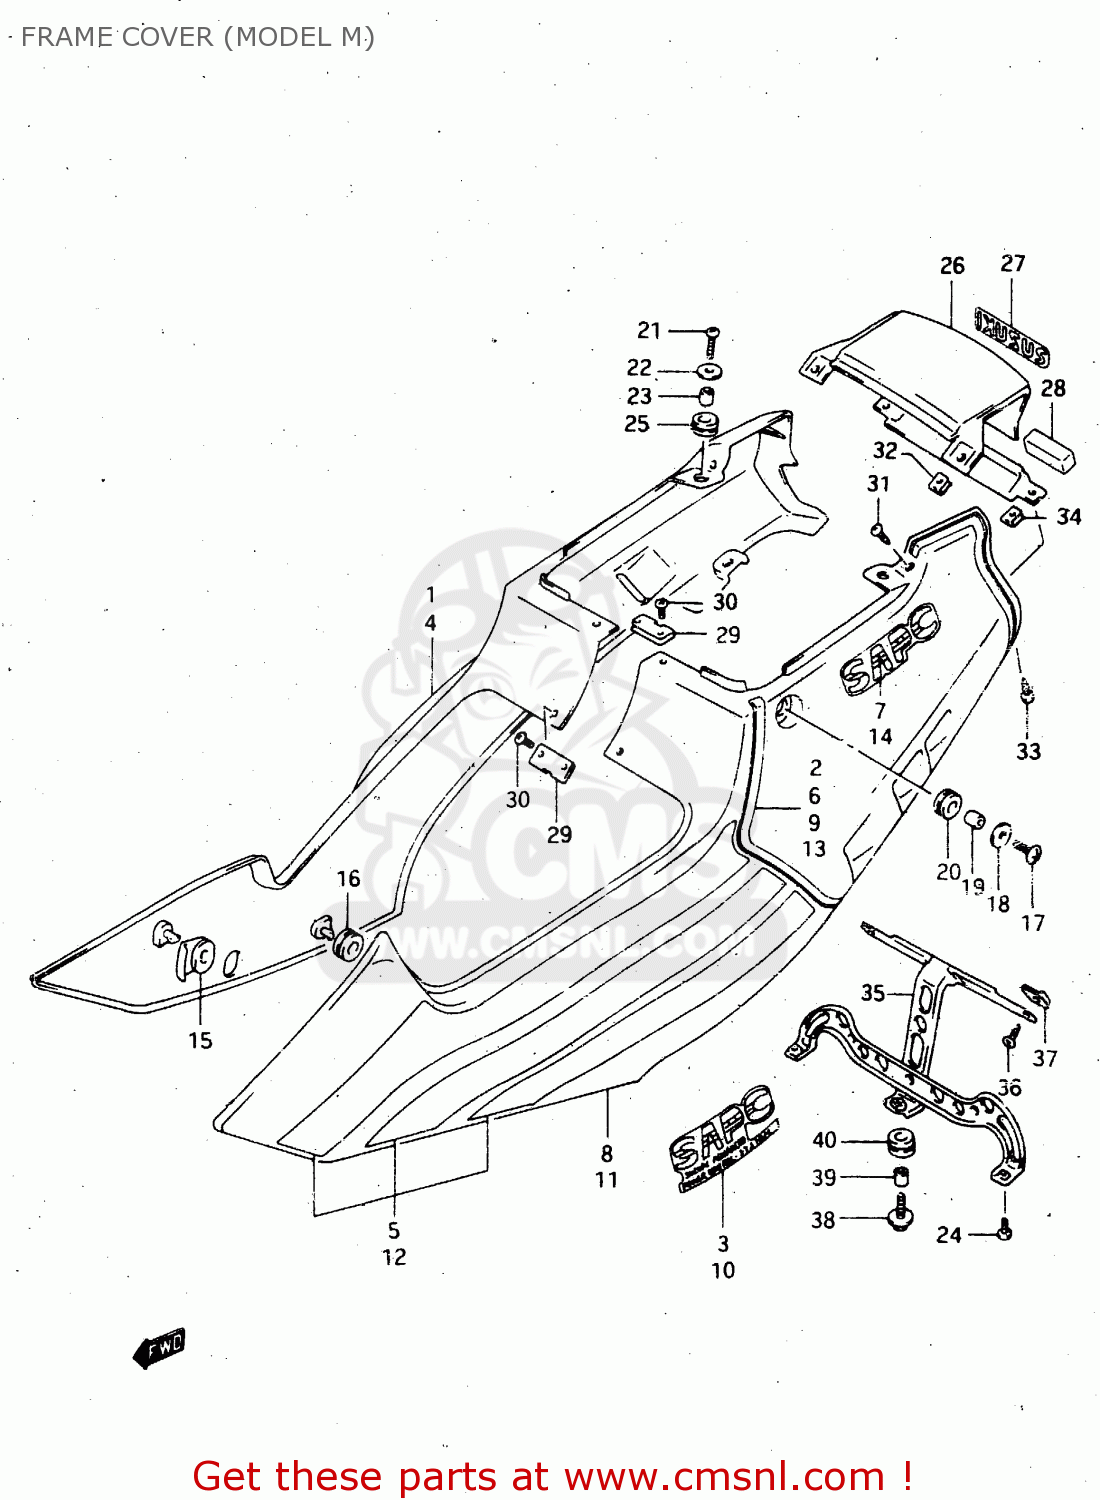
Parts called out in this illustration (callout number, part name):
1	COVER, FRAME RH
2	TAPE, FRAME COVER RH (SILVER)
3	EMBLEM, FRAME COVER
4	COVER, FRAME RH (WHITE)
5	TAPE SET, FRAME COVER RH
6	TAPE, FRAME COVER RH (BLUE)
7	EMBLEM,FRAME COVER
8	COVER, FRAME LH
9	TAPE, FRAME COVER LH (SILVER)
10	EMBLEM, FRAME COVER
11	COVER, FRAME LH (WHITE)
12	TAPE SET,FRAME COVER,L
13	TAPE, FRAME COVER LH (BLUE)
14	EMBLEM,FRAME COVER
15	CUSHION,FRAME COVER FR
16	CUSHION
17	SCREW(6X20)
18	WASHER(6.5X22X1.6)
19	SPACER (6.3X9.1X6.7)
20	CUSHION
21	SCREW(6X20)
22	WASHER (6.5X22X1.6)
23	SPACER (6.3X9.1X6.7)
24	SCREW (6X16)
25	CUSHION
26	COVER, FRAME CENTER (BLACK)
27	EMBLEM
28	RUBBER
29	NUT,FRAME COVER CTR
30	SCREW
31	SCREW, BRACKET
32	NUT
33	SCREW
34	NUT
35	BRACKET, TAIL LAMP REAR
36	SCREW
37	NUT
38	BOLT(6X20)
39	SPACER (6.1X8X9.5)
40	CUSHION
